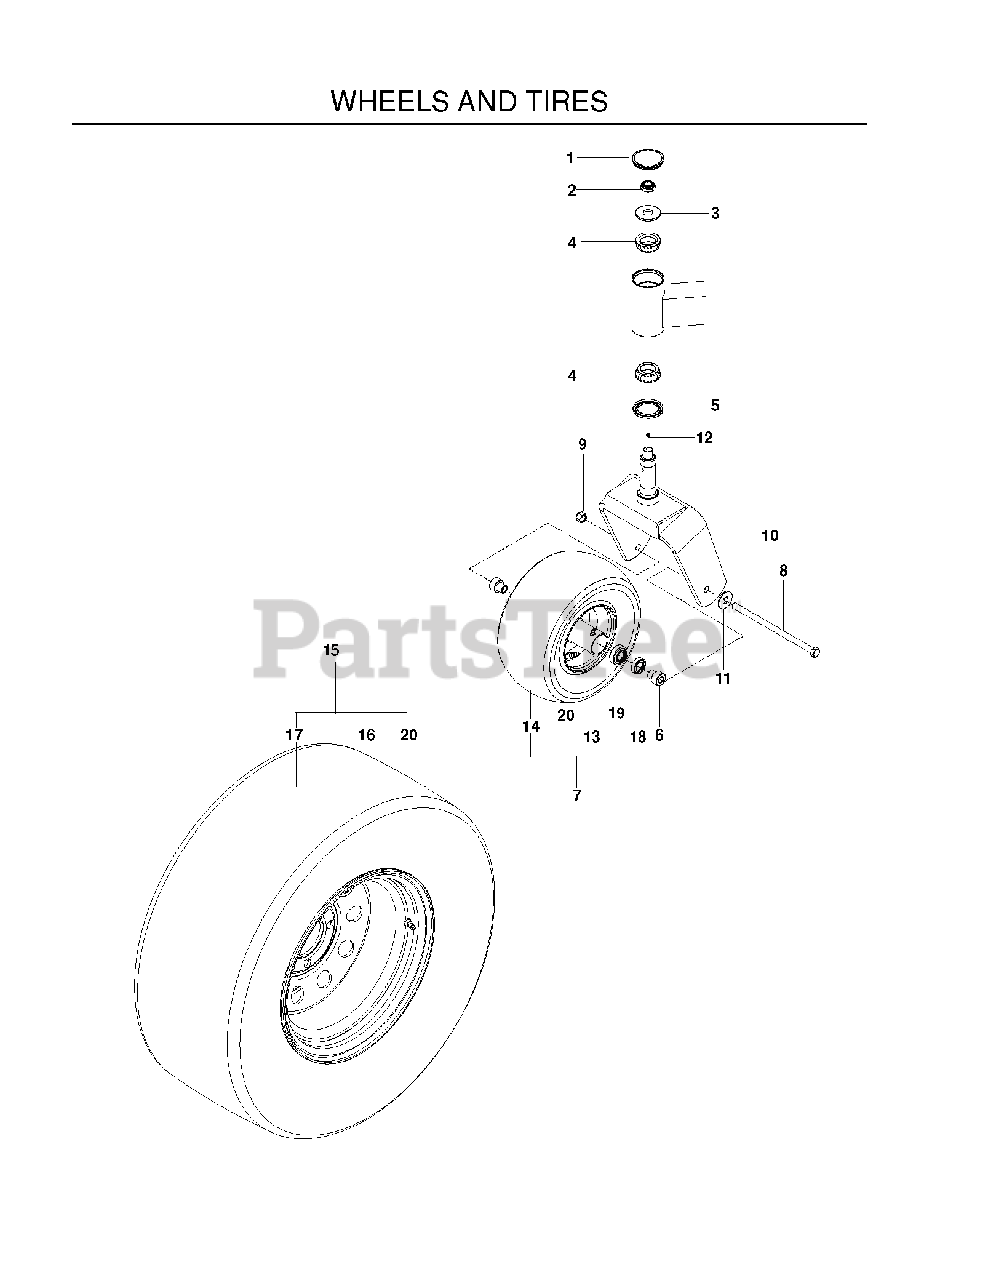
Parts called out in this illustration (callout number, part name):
1	CAP, DUST
2	NUT, 3/4-16 HEX THIN NYLOC ZD
3	WASHER, 3/4 HARDENED
4	BEARING, TAPPER ROLLER
5	SEAL, BEARING
6	AXLE SPACER
7	FRONT TIRE ASSY
8	HEX SCREW 1/2-13 X 9.5 GR5
9	NUT, 1/2-13 HEX FLG NYLOC ZD
11	WASHER 1/2" FLAT
13	ZERK
14	TIRE - SMOOTH
15	TIRE ASSY 24-12
16	RIM 2.5" NEG OFFSET 8.5" WIDE
17	REAR TIRE 24X12 TURFMASTER
19	TAPERED BEARING W/RACE
20	VALVE STEM TR-412
